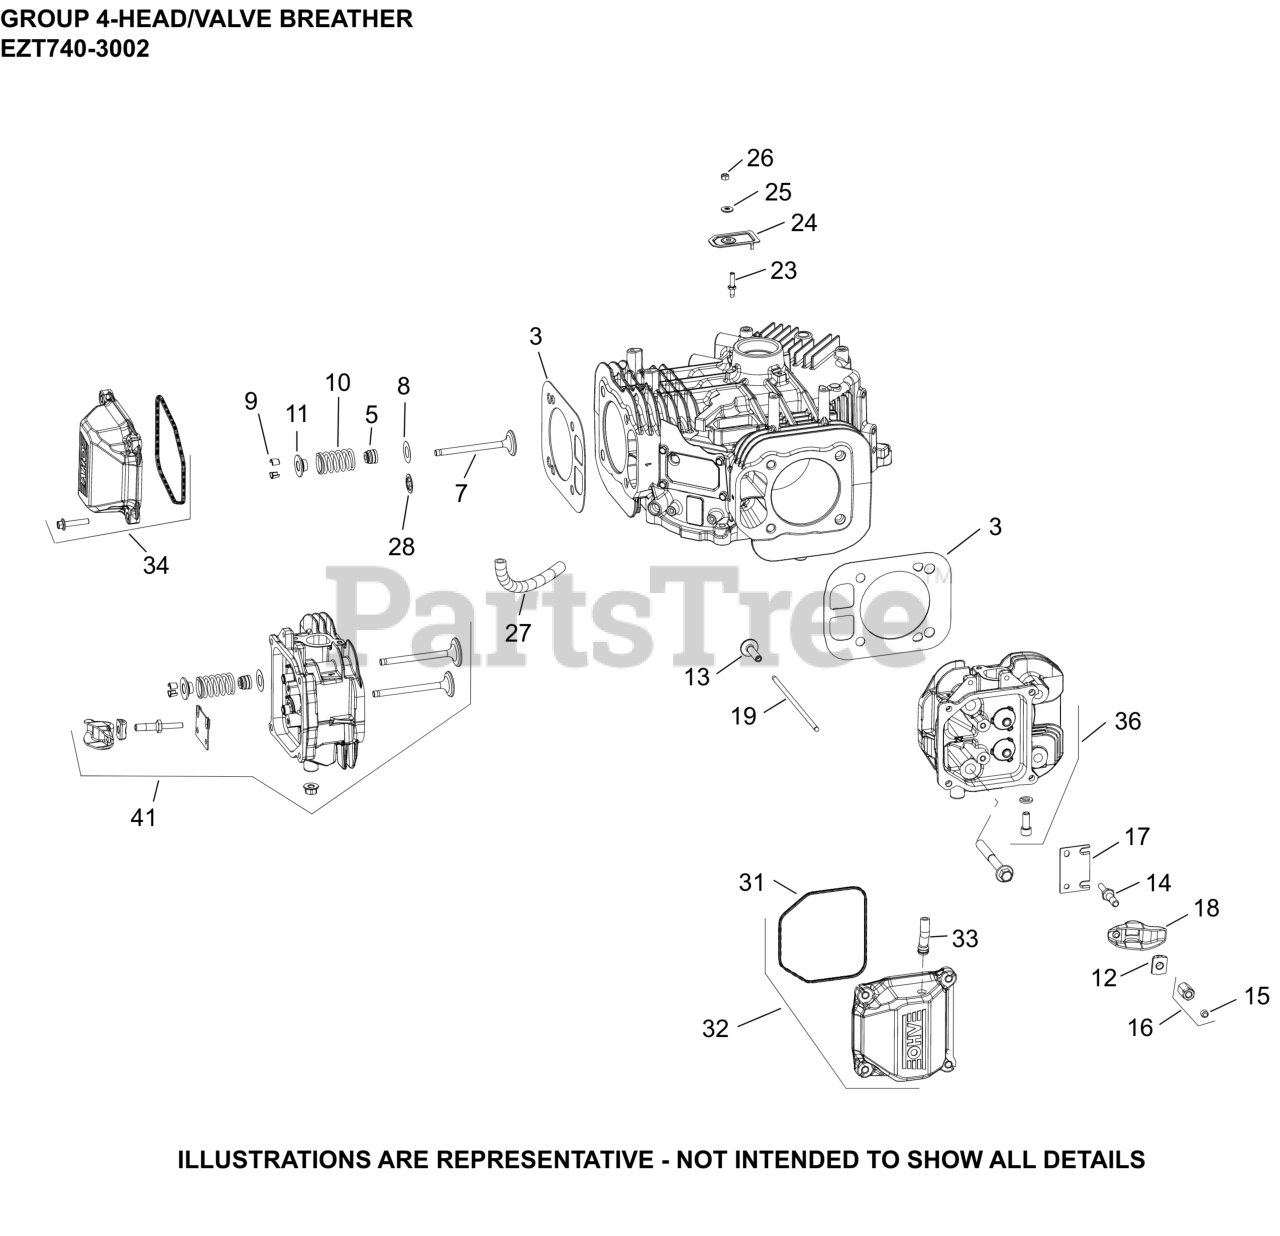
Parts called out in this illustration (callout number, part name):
3	KIT, GASKET CYLINDER HEAD
5	SEAL, VALVE BAND
7	VALVE, EXHAUST
7	VALVE, EXHAUST (.25)
8	SPACER (.010")
9	KIT, RETAINER
10	SPRING VALVE
11	CAP, VALVE SPRING
12	PIVOT, ROCKER ARM
14	STUD, ROCKER
15	SCREW, SET
16	HEX NUT ASSEMBLY
17	PLATE, GUIDE
18	ARM, ROCKER
19	ROD, PUSH
24	COVER, BREATHER REED
25	WASHER, SEALING
26	NUT, LOCK M5X.8
27	HOSE, BREATHER
28	RETAINER, VALVE GUIDE (KM)
31	O-RING (YELLOW), VALVE CO
32	KIT,BREATHER VALVE COVER (PLASTIC)
33	HOSE, FP-USE 32 326 07-S(PLASTIC COVERS)
34	KIT, VALVE COVER-PLAIN (PLASTIC)
36	KIT, HEAD #2 AND HARDWARE-(#1675521S)
41	KIT, CYLINDER HEAD #1
NI	VALVE, INTAKE (STD)
NI	VALVE, INTAKE (.25)-(#DSC)
NI	SCREW, HEX FLANGE M10 X 1.5-6g X 90mm
NI	SCREW, HEX FLANGE (M6 X 31.625 DOG PT)
